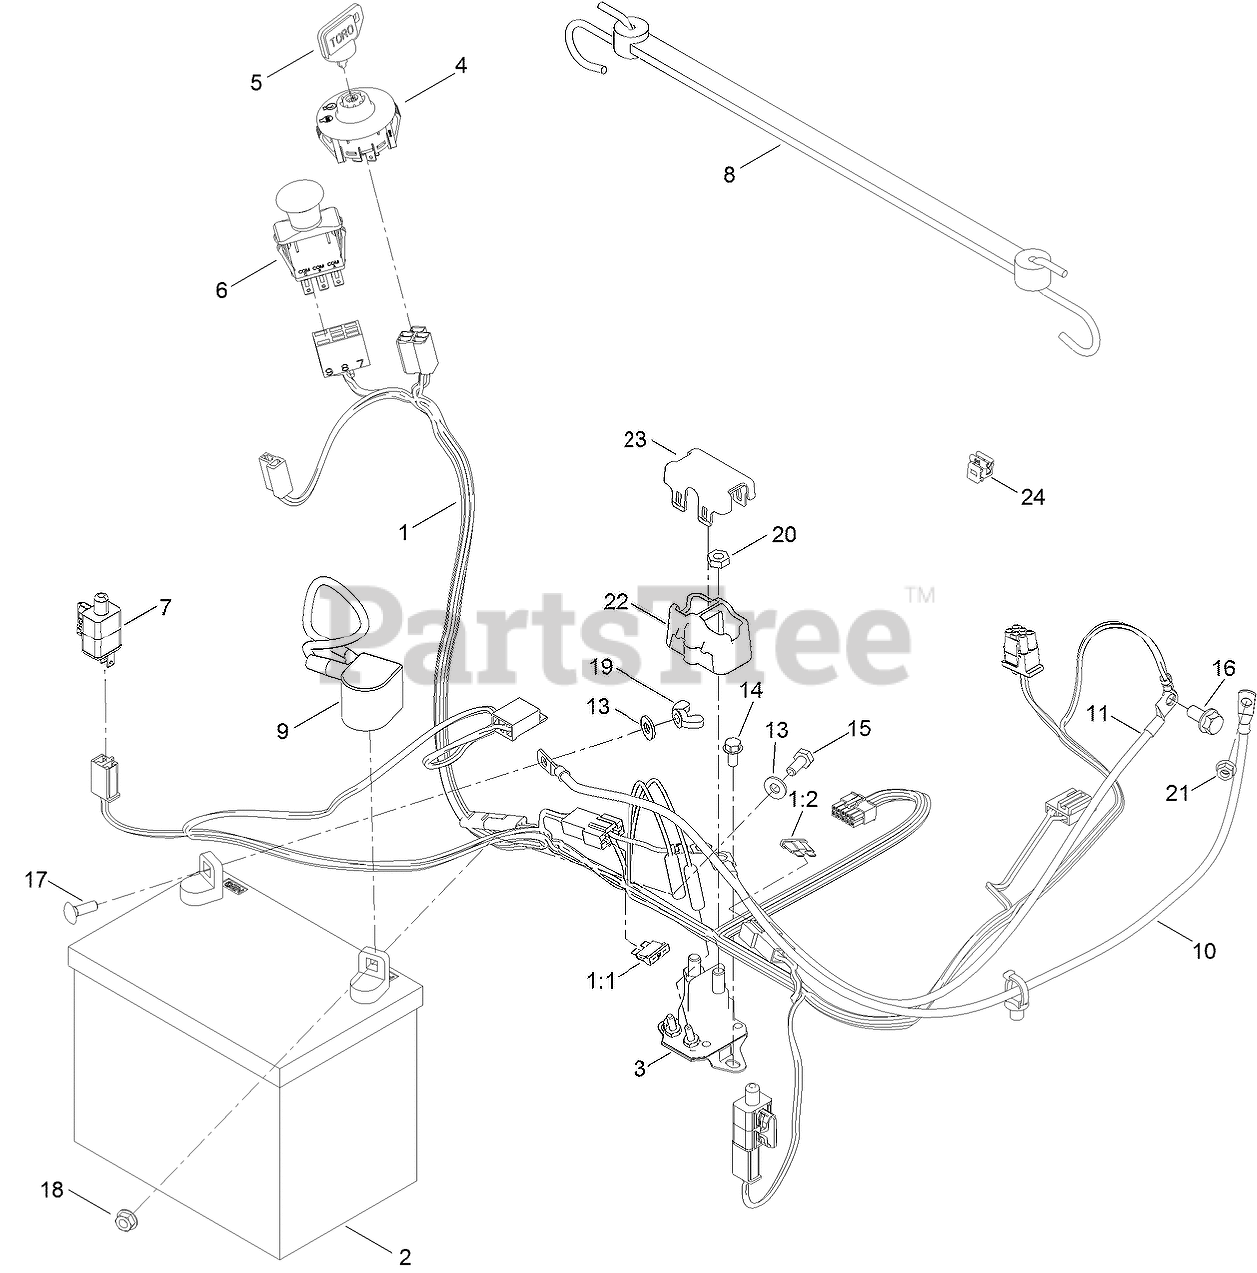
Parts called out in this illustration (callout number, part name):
1	HARNESS-WIRE
1:1	FUSE-BLADE, 15 AMP
1:2	FUSE-BLADE, 25 AMP
2	BATTERY
3	SOLENOID
4	SWITCH-IGNITION
5	KEY-IGNITION
6	SWITCH-PTO
7	SWITCH
8	STRAP-RUBBER
9	CABLE-BATTERY, POS
10	CABLE-BATTERY, RED (8 GAUGE)
11	CABLE-BATTERY, BLACK
13	WASHER-FLAT
14	SCREW-HWH
15	SCREW-HH
16	SCREW-HHF
17	BOLT-CARR
18	NUT-HF
19	NUT-WING
20	NUT-JAM
21	NUT-HF
22	COVER-SOLENOID
23	CAP-SOLENOID
24	CLIP-HARNESS
